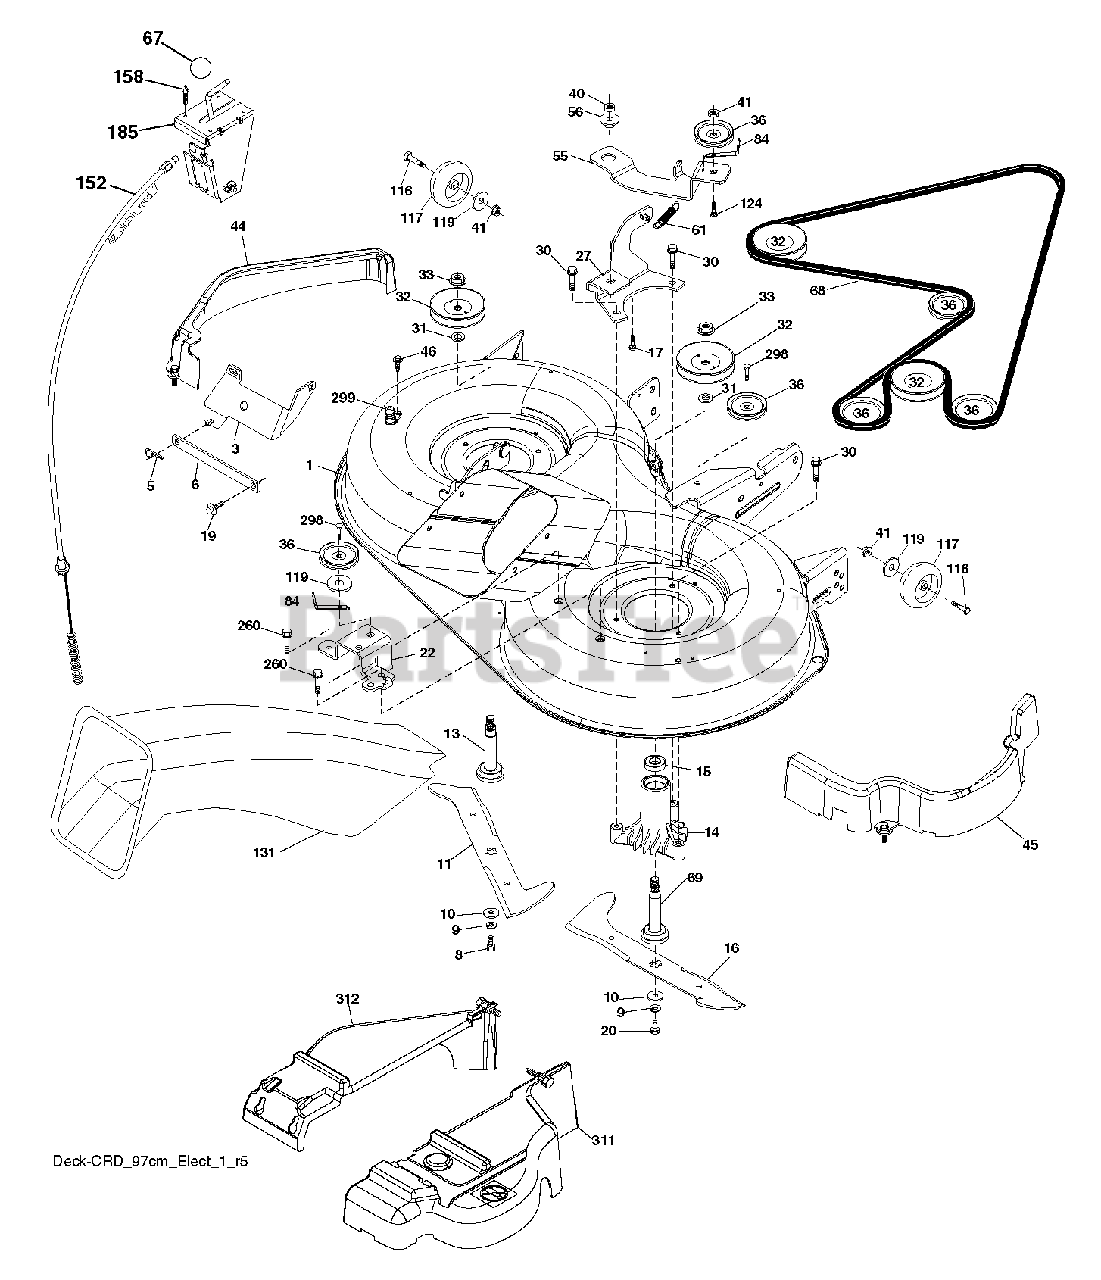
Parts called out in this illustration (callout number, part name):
3	BRACKET.ASM.BAR.SWAY.CHASS
5	RETAINER-SPRNG RB
6	BAR SWAY
9	LOCKWASHER
10	WASHER.BLADE
11	BLADE.3N1.LH.CRD.97
13	SHAFT ASM VENT
14	HSG MANDREL
16	BLADE.3N1.RH.CRD.97
17	BOLT.3/8-14X1.25
19	BOLT SHD 5/16-18
22	BRACKET.SUPT.IDLER.REAR.RH
27	BRACKET.ASM.SUSP.REAR.RH.
30	SCREW, WASHER HEAD
31	WASHER.SPACER.MANDREL
32	PULLEY MANDREL
33	NUT.FLANGE.LOCK.TOP
36	PULLEY.IDLER.4.25
40	LOCKNUT
41	NUT LOCK FLG 3/8-16 UNC
46	SCREW.1/4-20X5/8
56	SPACER.RETAINER.MOWER
67	KNOB T (3/8 HOLE)
68	BELT.DRIVE.CRD.97.2010
69	SHAFT.ASM.W/LWR.BRG.RH.THREAD
84	KEEPER, BELT IDLER
116	BOLT.SHOULDER.3/8-16X3-5/8
117	WHEEL. GUAGE RALLY
124	BOLT.3/8-16X1.50
131	CHUTE BAGGER
158	SCREW
185	HEAD ASM. CABLE CLUTCH
260	SCREW 3/8-16X1/2
298	SCREW LT
299	PORT.WASHOUT
